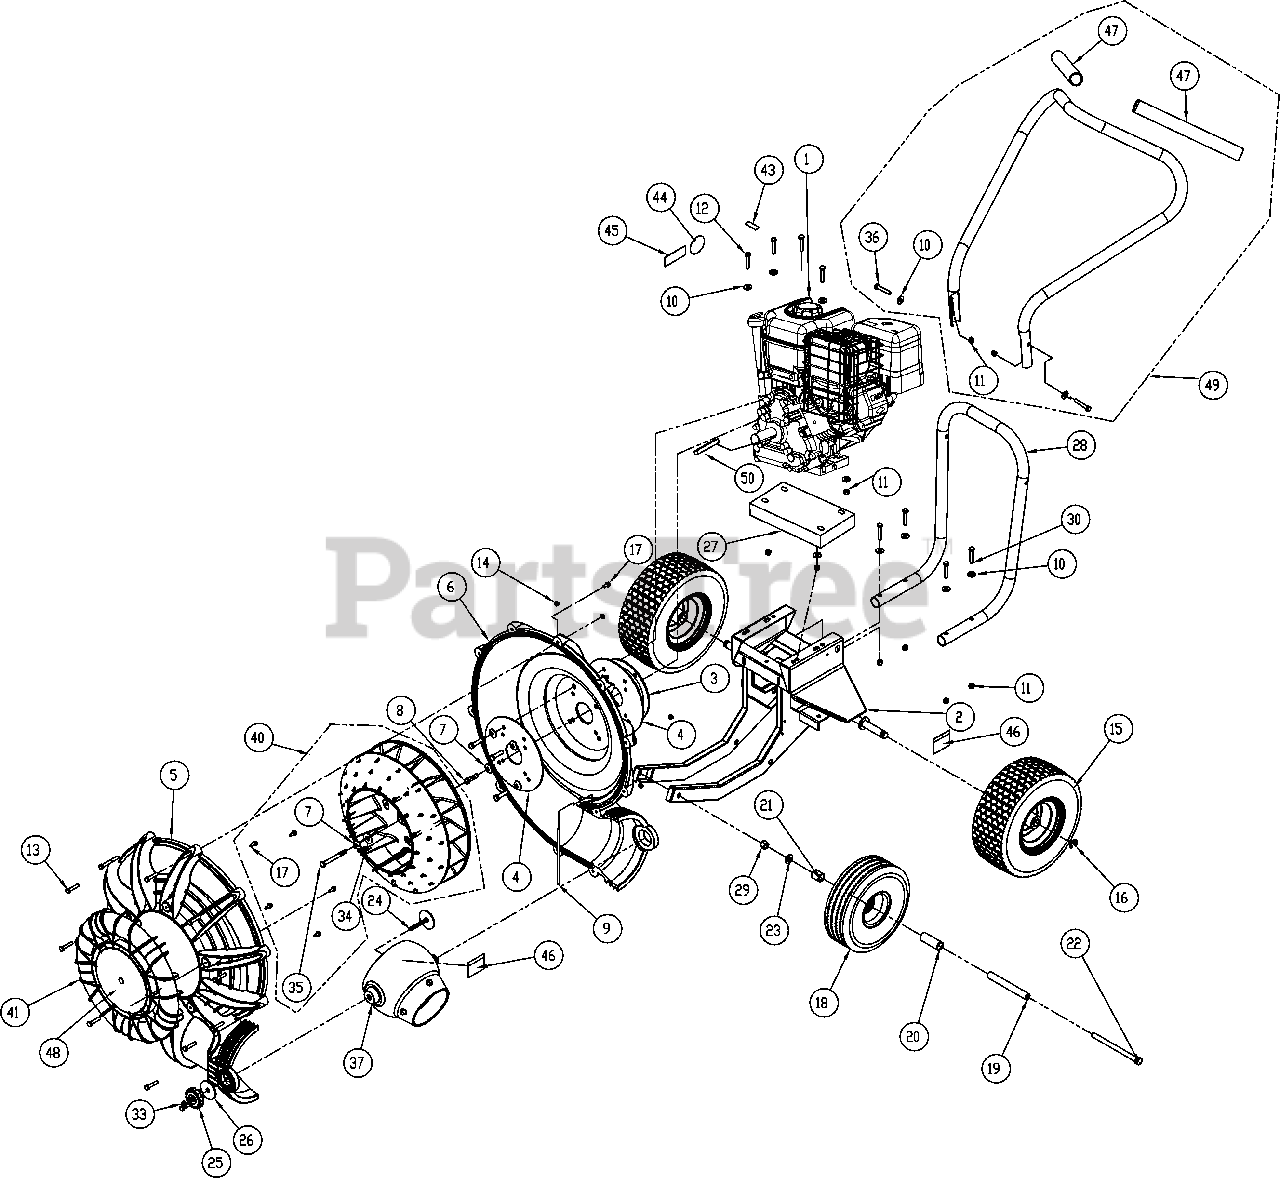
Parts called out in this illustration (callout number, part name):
1	ENGINE 8 HP B&S
2	BASE ENGINE WA
3	SPACER RING ENGINE
4	PLATE REINFORCE HOUSING
5	HOUSING FRONT MOLDED
6	HOUSING BACK MOLDED
7	WASHER LOCK 3/8 TWISTED TOOTH
7	WASHER LOCK 7/16 S/T MED
8	SCREW CAP 3/8-16X1 1/2 ZP
9	ROD HAND STOP
10	WASHER 5/16 FLATWASHER Z/P
11	NYLON INSERT LOCKNUT 5/16-18
12	SCREWCAP 5/16-18 X 2.5 ZP
13	SCREWCAP 1/4-20 x 1 1/2
14	NUT FLANGE 1/4-20
15	WHEEL & TIRE 13" X 5" PNEUMATIC
16	RING RETAINING 3/4
17	SCREW SELF-TAP 5/16 NC X 3/4 HEX
18	WHEEL ASSY 10 " PNEUMATIC
19	SPACER FRONT AXLE
20	SPACER LH WHEEL
21	SPACER RH WHEEL
22	SCREWCAP 1/2-13 x 7"
23	WASHER FLAT 1/2" SAE
24	WASHER W/BOLT WA
25	KNOB 3/8-16 SOLID HUB
26	WASHER 2.25 OD x .515 ID x .134 ZP
27	ENGINE SPACER
28	HANDLE LOWER
29	NYLON INSERT LOCKNUT 1/2-13
30	SCREWCAP 5/16-18 X 1.75 ZP
33	NUT LOCK 3/8-16 LT WT THIN ZP
34	WASHER 1.5 O.D.X 0.45 I.D. X 0.25
35	SCREWCAP 7/16-20 X 3.5 GR.8 55-60 ft-lbs
36	SCREWCAP 5/16"-18 X 2" ZP
37	DIRECTOR CONE 4"
40	IMPELLER ASSEMBLY 17"
41	GRILL FRONT BLOWER
43	LABEL HOT ENGINE
44	LABEL READ
45	LABEL EAR EYE BREATHING
46	LABEL DANGER FLYING DEBRIS
47	GRIP 1-1/4" ID x 13"
48	LABEL FORCE
49	HANDLE ASSY UPPER
50	Key 1/4" SQ x 2.25
